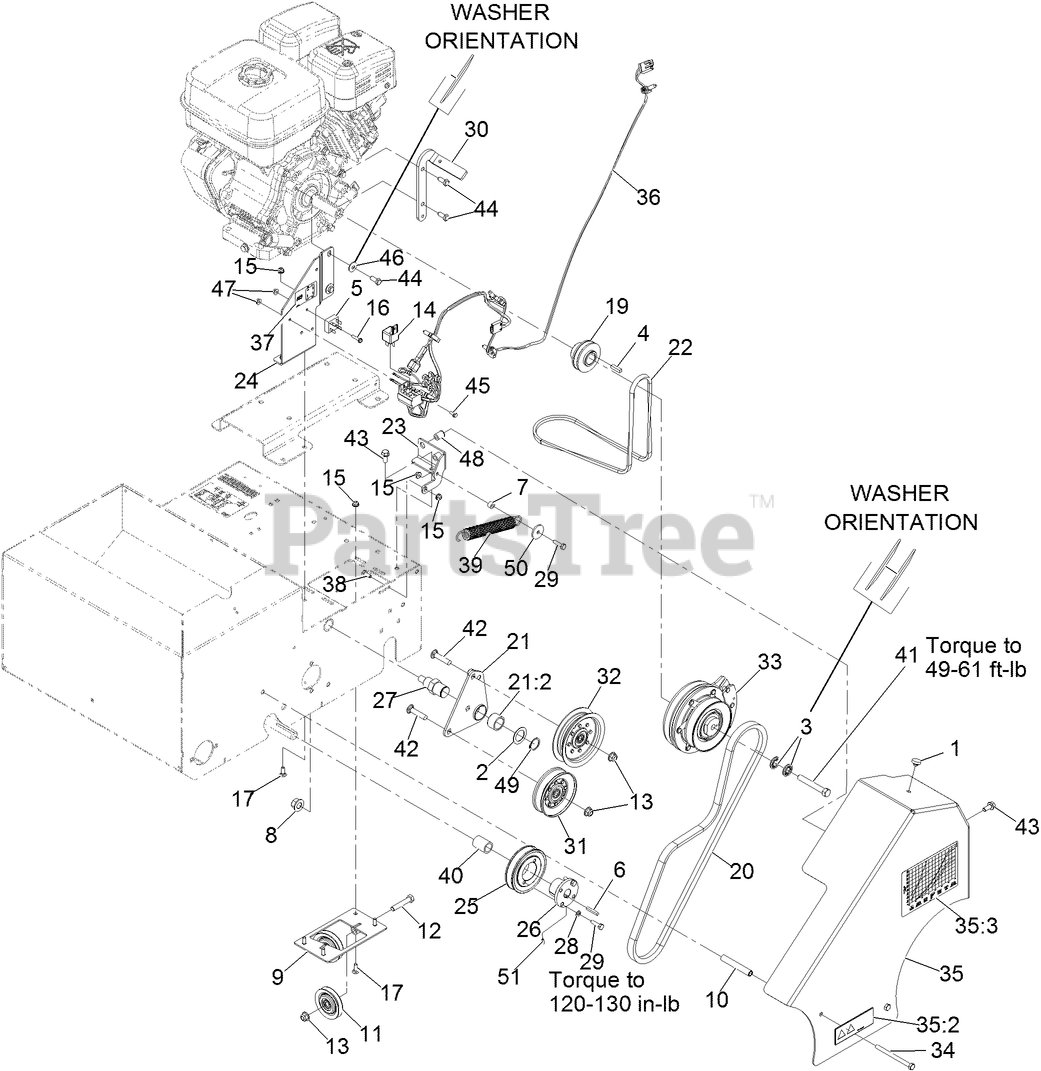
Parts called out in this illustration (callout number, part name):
1	BUMPER
2	WASHER-SPACER
3	Washer-Spring Disc 7/16
4	Key-Machine 1/4 x 1/4 x 1
5	RECTIFIER-BRIDGE
6	Key-Machine 3/16 x 3/16 x 1 1/4
7	Spacer
8	Nut-Lock 1/2-13
9	PULLEY-TENSION
10	SPACER-KICKSTAND, LONG
11	PULLEY-IDLER
12	Screw-HH 3/8-16 x 2
13	Nut-Nyloc 3/8-16 Flg
15	Nut-Nyloc 1/4-20 Flg
16	SCREW-HWH
17	Bolt-Carriage 1/4-20 x 3/4
19	PULLEY-MULE DRIVE
20	BELT-SEEDER, CLUTCH
21	IDLER ARM ASM
21:2	BUSHING
22	BELT-MULE DRIVE
23	BRACKET-SPRING
24	SUPPORT-ENGINE
25	SHEAVE-TAPER LOCK
26	BUSHING-TAPER LOCK
27	PIVOT-IDLER
28	Washer-Lock 1/4
29	Screw-HH 1/4-20 x 1
30	STOP-CLUTCH
31	PULLEY-IDLER V
32	PULLEY-IDLER FLAT (4.06-INCH)
33	CLUTCH-ELECTRIC
34	Screw-HH 5/16-18 x 4
35	BELT GUARD ASM
35:2	DECAL-DANGER
35:3	DECAL-SEED GRAPH
36	HARNESS-SLICER/SEEDER
37	DECAL-BRIDGE RECTIFIER
38	Screw-HH 1/4-20 x 5/8
39	SPRING-EXTENSION
40	SPACER
41	Screw-HH 7/16-20 x 3
42	Bolt-Carriage 3/8-16 x 1 3/4
43	Screw-HH FLG 5/16-18 x 3/4
44	Screw-HH 5/16-24 x 3/4
45	SCREW-HWH
46	Washer-Spring Disc
47	Nut-Flange #10-24 Top Lock
48	NUT-INSERT
49	Ring-Retaining
50	WASHER
51	SCREW-SET, HS
